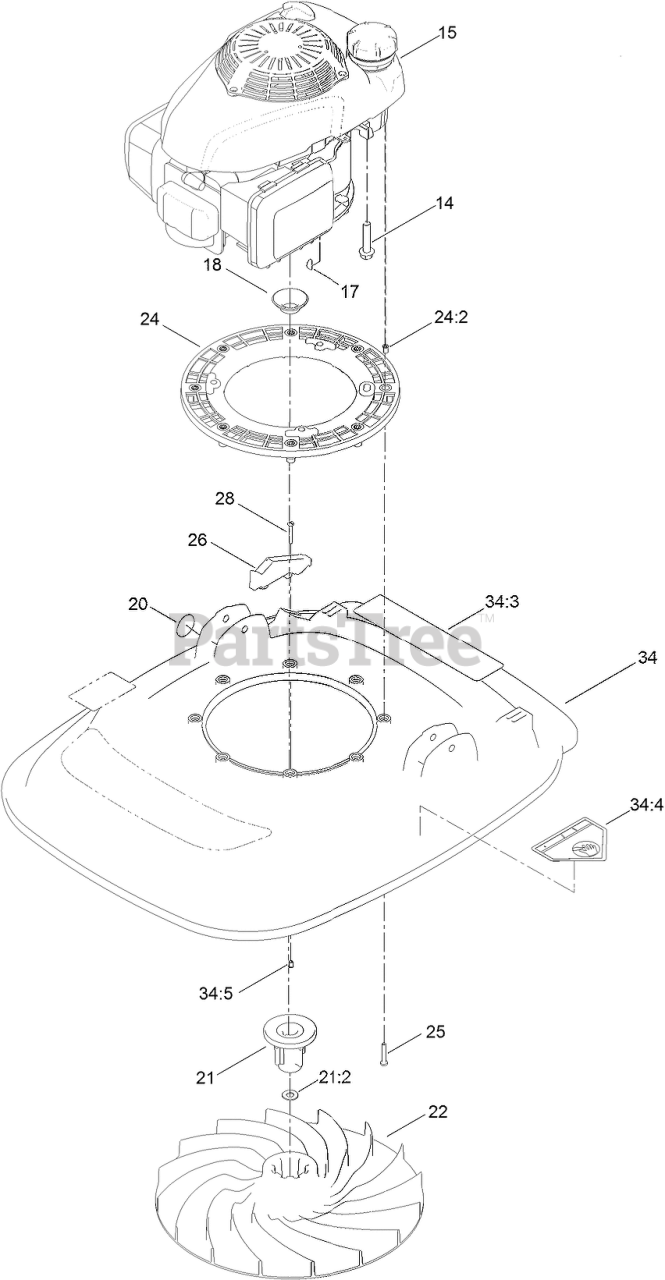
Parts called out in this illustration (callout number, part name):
14	SCREW-TAPTITE
15	ENGINE-HONDA
17	KEY-WOODRUFF
18	PROTECTOR-SEAL, OIL
20	DECAL
21	DRIVE AND SPACER ASM
21:2	WASHER-PLAIN
22	IMPELLER
24	FRAME-ENGINE
24:2	INSERT-BRASS
25	SET-SCREW
26	BRACKET
28	SCREW
34	DECK ASM
34:3	DECAL-WARNING
34:4	DECAL-DANGER
34:5	INSERT
